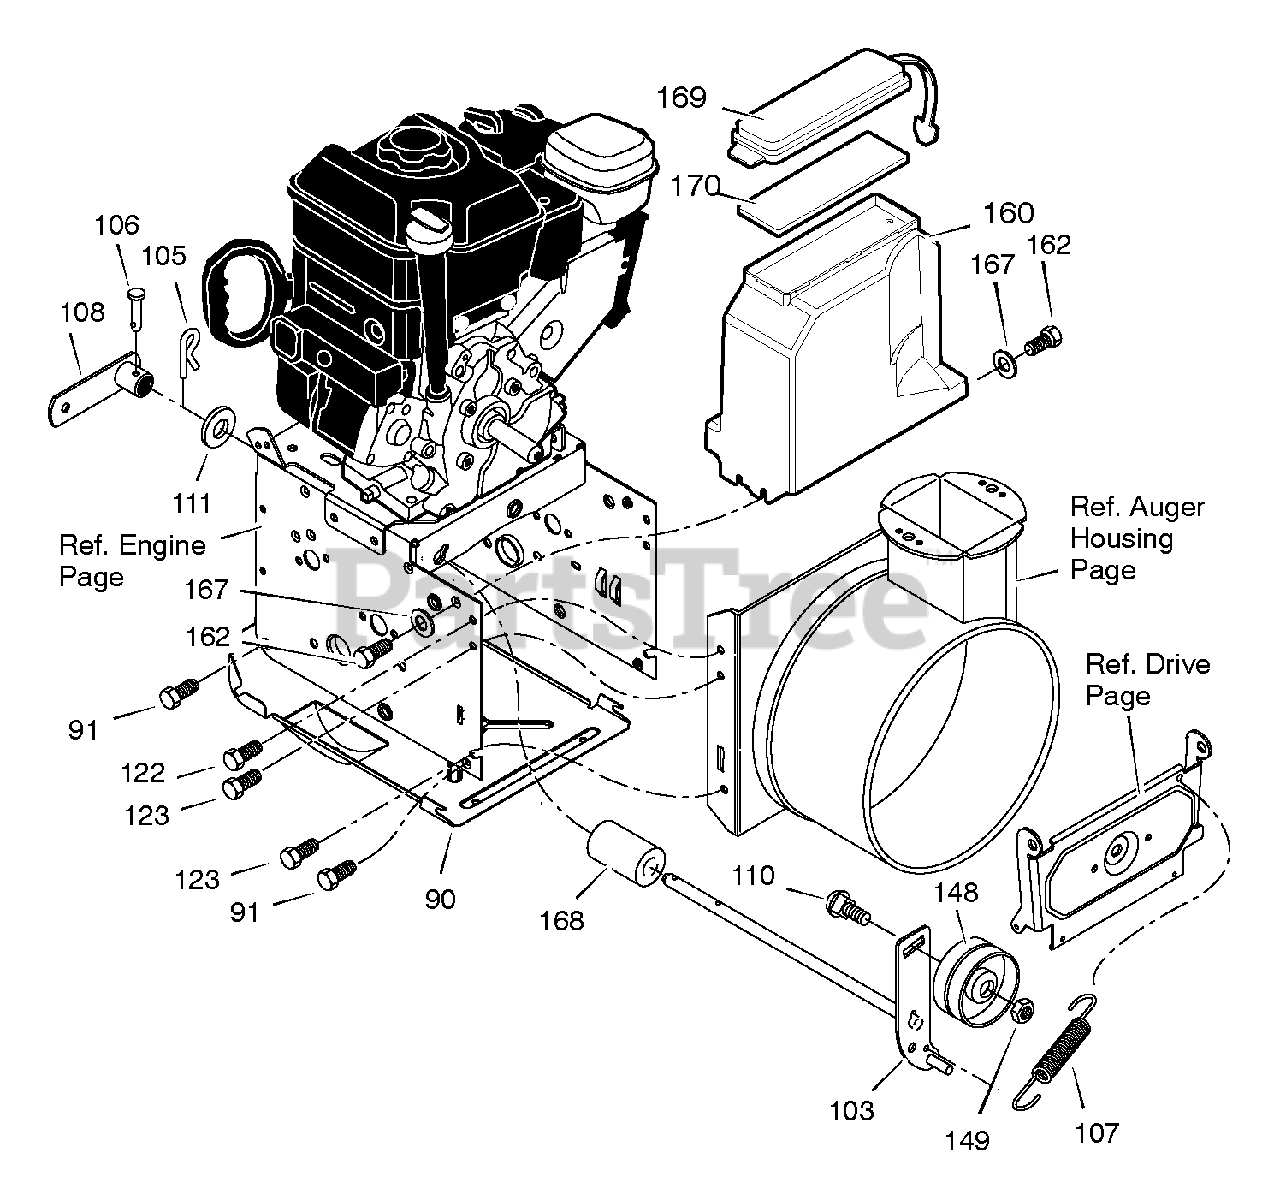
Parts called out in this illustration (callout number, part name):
90	COVER, BOTTOM
91	SCREW
103	IDLER, AUGER
105	PIN, HAIR
106	PIN, CLEVIS
107	SPRING, TENSION
108	SPRING ATTACH
110	BOLT, CARRIAGE
111	WASHER, FLAT
122	SCREW, TAP
123	SCREW, TAP
148	PULLEY, IDLER
149	NUT, JAM 3/8-16
160	COVER, BELT
162	SCREW, TAP
166	WASHER, FLAT
169	LID, TOOL BOX
170	PAD, FOAM
